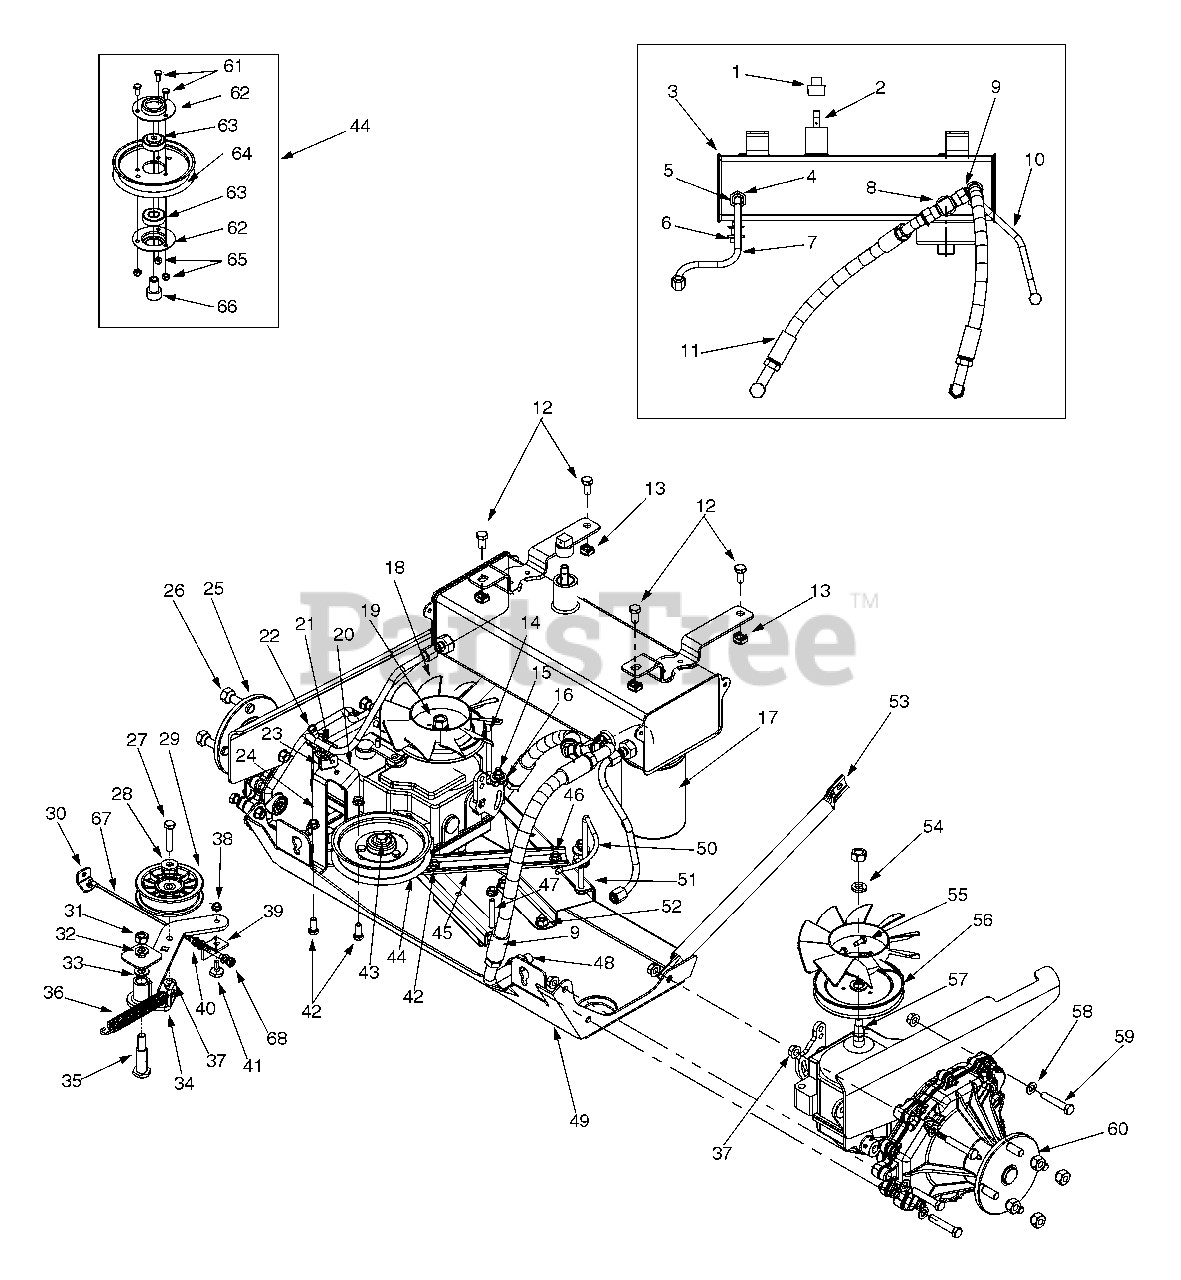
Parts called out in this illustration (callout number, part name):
1	Pipe Plug
2	Pipe Dipstick
6	Drain Plug
7	Inlet Tube LH
8	Tee Fitting
9	Outlet Hose RH
10	Inlet Tube RH
11	Outlet Hose LH
12	Hex Cap Screw 3/8-16 x .75
13	Retainer Nut 3/8-16
14	Belt Retainer Rod RH
15	Hex Cap Screw 5/16-18 x 2.5
16	Flat Washer 5/16
17	Filter Element
18	Fan Blade
19	Hex Nut 1/2-20
20	Mounting Pulley Bracket
21	Roller Cable
22	Hex Shoulder Screw 1/4-28 x .375
23	Retainer Cable Bracket
24	Lock Nut 1/4-28
25	Complete Transmission Assembly LH
26	Lug Nut
27	Hex Cap Screw 3/8-16 x 1.75
28	Flat Washer .385 ID x 1.0 OD
29	Flat Idler Pulley 3.5 OD
30	Mounting Bracket Cable
31	Hex Nut 7/16-14
32	Lock Washer 7/16
33	Flat Washer .469 ID x .875 OD
36	Extension Spring 6.12 Lg
37	Flange Lock Nut 3/8-16
38	Hex Nut 1/4-26
39	Lock Washer 1/4
40	Flat Washer .283 ID x .75 OD
41	Hex Cap Screw 1/4-28 x 1.25
42	Hex Cap Screw 5/16-18 x .75
43	Hex Cap Screw 3/8-16 x 2.25
44	Idler Pulley Assembly 5.0"
47	Hex Cap Screw 5/16-18 x 2.0
48	Connection Fitting 1/2 x 3/8
49	Skid Plate Assembly
50	Belt Rod LH
51	Support Pump Assembly
52	Carriage Bolt 3/8-16 x .75
55	Hex Washer Screw #12-24 x .625
56	Transmission Pulley
57	Wire Ring
58	Flat Washer
59	Hex Cap Screw 3/8-16 x 2.0
60	Complete Tranmission Assembly RH
61	Hex Cap Screw 1/4-20 x .62
62	Bearing Cup
63	Ball Bearing
64	Idler Pulley 5.0"
65	Hex Lock Nut 1/4-20
66	Idler Spacer
67	Declutching Cable
68	Jam Nut 5/16-18
